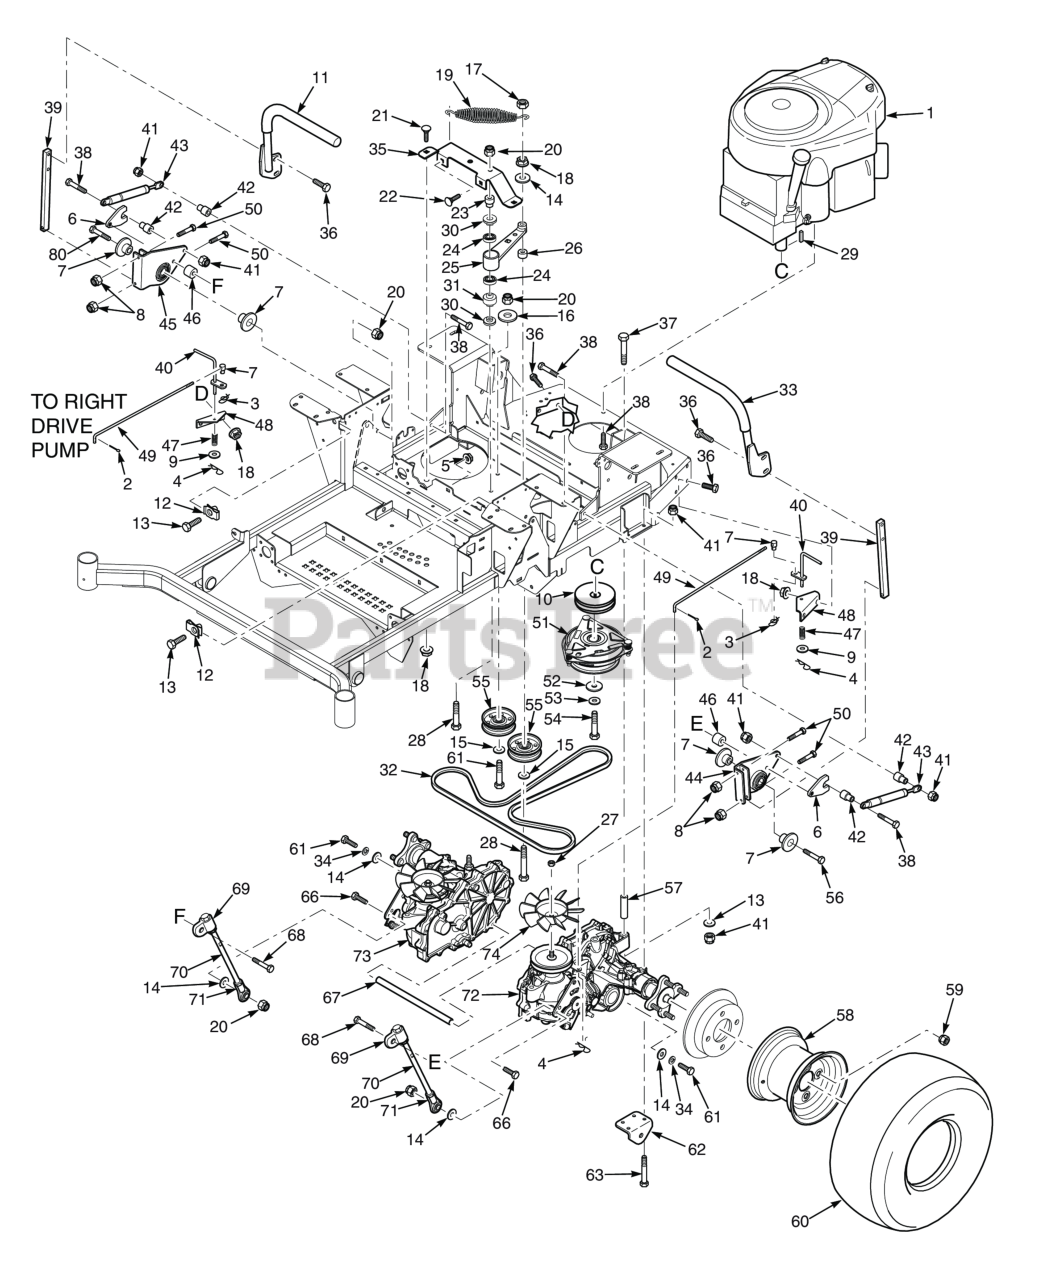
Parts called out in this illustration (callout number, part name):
1	Engine, Kohler - 23CV
2	COTTER PIN, 3/32 X 1"
3	Pin, Rue Cotter 3/8" Diameter
4	HAIR PIN, .08 DIAMETER X 1-3/16"
5	Nut, Serrated Flange 5/16-18 (Right Front Engine Mounting, Briggs and Kohler Only)
6	Nut, Control Linkage
7	Spacer, Linkage
8	HEX, NUT, ELASTIC STOP LOCK, 1/4-20
9	Flatwasher, 1/4" (.312 x .750 x .065")
10	Pulley, 4-1/2" OD - 1.125 Bore (SPZ52H)
11	Handle Bar Assembly RH, w/Grip
12	U-Nut, 3/8-16 (short)
13	Bolt, Hex Head 3/8-16 x 1-1/4" Special Lock
14	Flatwasher, 3/8" Special (.391 x .938 x .105)
15	Flatwasher, 3/8 (.391 x .938 x .105 HD) Grade 8
16	Flatwasher, 3/8-.406 x 1-1-1/2 x 7 Gauge
17	Bolt, Hex Head 3/8-16 x 1" Ser. Flg.
18	NUT, 3/8-16 SERRATED FLANGE HEX HEAD
19	Spring, Transmission Idler
20	HEX NUT, ELASTIC STOP LOCK, 3/8-16
21	Bolt, Carriage 3/8-16 x 3/4"
22	Bolt, 5/16-18 x .75 RHSN Carriage
23	Shaft Pivot, Idler Arm
24	BEARINGS, BALL, NEUTRAL RETURN
25	Trans. Idler Arm Assy. (Includes 24, 79)
26	Spacer, Idler Pulley - SFZ52
27	Fan Nut (order through Hydro-Gear)
28	Capscrew, Hex Head 3/8-16 x 3.25"
29	Key, 1/4" x 1/4" x 2-3/4" Pulley Mtg.
30	Spacer, Controls
31	Spacer, Bearing
32	Belt, Transmission Drive - SFZ52
33	Handle Bar Assembly LH, w/Grip
34	Lockwasher, 3/8" Spring, Kawasaki FX / FT & FT-EFI / B&S 32BV
35	Support, Idler Arm
36	Capscrew, 3/8-16 x 1.0" Serrated Flange Hex Hd
37	HEX HEAD BOLT, 5/16-18 X 5"
38	Bolt, Hex Head 5/16-18 x 1-1/2" (Right Front Engine Mounting, Briggs and Kohler Only)
39	Bar, Control Lever
40	Dump Valve Lever
41	HEX NUT, ELASTIC STOP LOCK, 5/16-18
42	Spacer, Pump Dampener
43	Gas Damper
44	Control Link, LH
45	Control Link, RH
46	Spacer, Idler Pulley - SFZ52
47	Spring, Dump Valve Link
48	Bracket, Dump Mounting
49	Rod, Brake Adjustment
50	Bolt, Hex Head, 1/4-20 x 1-1/2"
51	Electric Clutch Assembly - SFZ52 & SFZ61
52	Flatwasher, 7/16-.469 x 1.75 x .25 (48, 52)
53	Lockwasher, 7/16� Spring
54	Bolt, Hex Head 7/16-20 x 1-1/2" Patch Kawasaki 22FX & 23FX
55	Pulley, 3-1/2" Dia.
56	Capscrew, Hex Head 3/8-16 x 2.0"
57	Spacer, Axle - SFZ52
58	Rim w/Valve Stem, (Scag Gold) - SPZ52H
59	Wheel Nut, 1/2-20 x 13/16
60	Wheel Assembly, 22 x 10.5-12 (SPZ52)
61	Capscrew, Hex Head 3/8-16 x 2-1/2"
62	Bracket, Push Arm Link
63	Bolt, Hex Head 5/16-18 x 3.00"
64	Clip, Brake Lever (order through Hydro-Gear)
65	Lever, Brake (order through Hydro-Gear)
66	Bolt, Hex Head 3/8-16 x 1-1/2" B&S 32BV
67	Spacer, Axles
68	Capscrew, Hex Head 3/8-16 x 2.0"
69	Rod End, Adjustable 3/8-24
70	Linkage, Pump - SFZ52
71	Stake, Rod End Assembly
72	Transaxle Assy., LH (ZL-GCEC-SLKF-1NTX) SPZ52H
73	Transaxle Assy., RH (ZL-KCEC-SLKG-1NTX) SPZ52H
74	Fan (order through Hydro-Gear)
